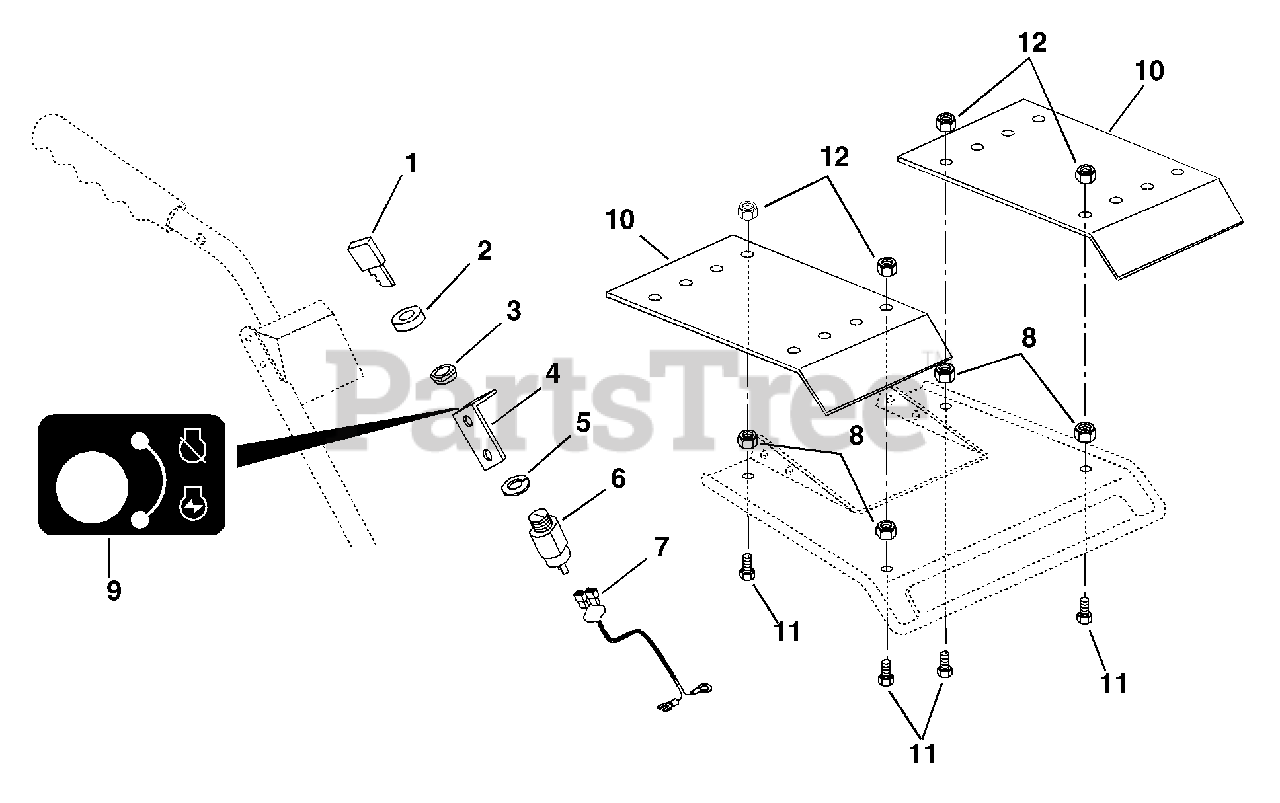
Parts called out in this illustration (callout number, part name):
1	KEY -W/CAP
2	CAP - IGNITION SWITCH
3	NUT-PANEL .625-32 GRECO
4	BRACKET, COMMON
5	WSHR-LK-INT .625X.045 YWZC
6	KEY SWITCH ASSEMBLY
7	WIRE HARNESS 301
8	@NUT-LK-CTR .31-18 YWZC
9	DECAL - TILLER SWITCH
10	SHIELD EXTENSION
11	@BLT-HEX .31-18X.75 GR5 YWZC
12	@NUT-LK-NYL .312-18 YWZC
